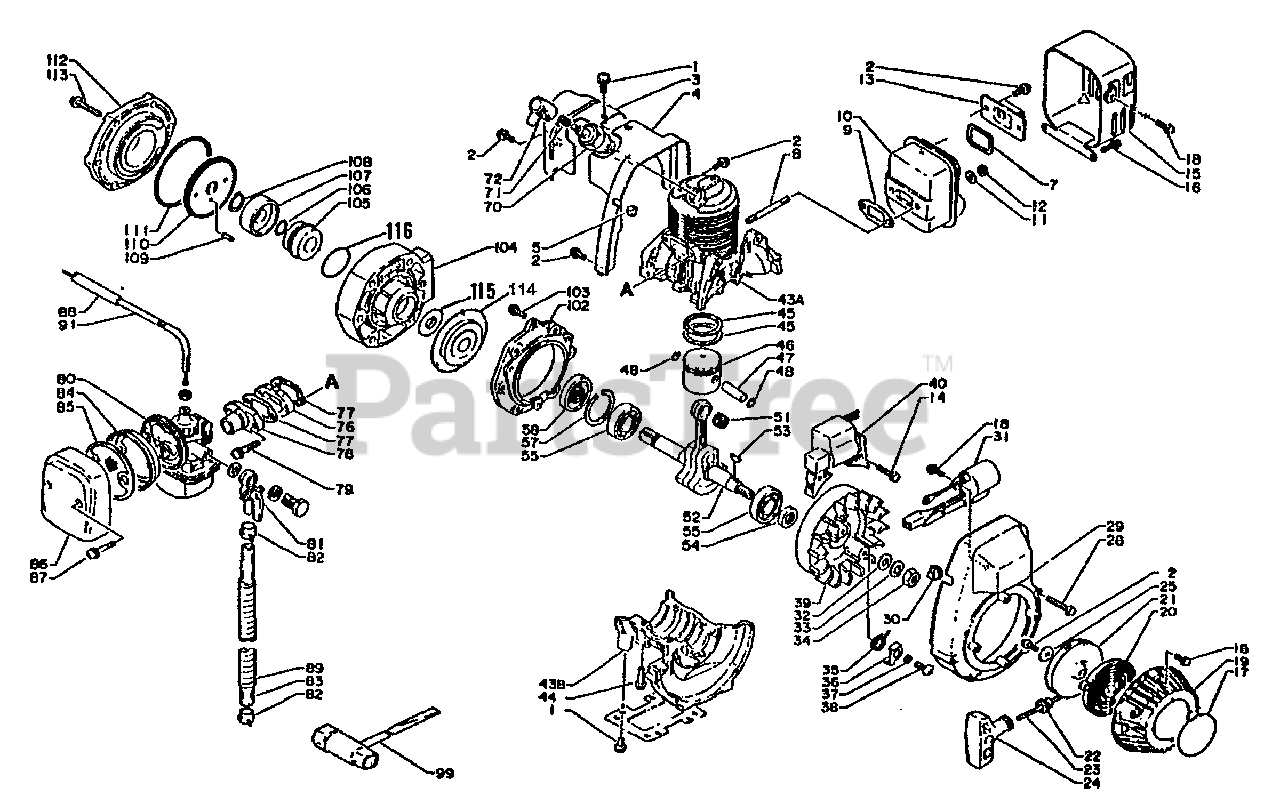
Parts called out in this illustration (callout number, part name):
1	SCREW 5×10
2	SCREW 4×10
3	PLATE, GUIDE
4	COVER, CYLINDER
7	GASKET, EXHAUST
8	BOLT, STUD
9	GASKET, MUFFLER
11	WASHER 5.5×12×0.8
12	NUT, LOCK M5
13	COVER, MUFFLER
14	SCREW 4×20
15	COVER, MUFFLER
16	SCREW 4×12
17	LABEL, ECHO
18	SCREW 4×14
19	CASE, RECOIL STARTER
20	SPRING, RECOIL
21	REEL, ROPE
22	GUIDE, ROPE
23	ROPE, STARTER 3.0×850
24	GRIP, STARTER
25	WASHER 4.1×15.5×1T
28	SCREW 4×40
29	COVER, FAN
31	COIL, IGNITION
32	WASHER 8.5×16×1.2
33	WASHER, SPRING 8
35	SPRING, RATCHET
36	PAWL, STARTER
37	SPACER 5.2×8×2.1
38	SCREW 5×14
39	FLYWHEEL
40	COIL, IGNITION
43	CASE, CYLINDER SET
43A	CASE, CYLINDER SET
43B	CASE, CYLINDER SET
44	SCREW 5×30
45	RING, PISTON
47	PIN, PISTON
48	RING, SNAP
51	BEARING, NEEDLE
52	CRANKSHAFT
54	SEAL, OIL
55	BEARING, BALL - 6201 C3
57	RING, SNAP Ø32
58	SEAL, OIL 12
70	SPARK PLUG - BM6A
71	TERMINAL, SPARK PLUG CAP
72	CAP, SPARK PLUG
76	INSULATOR
78	ADAPTER, INTAKE
79	SCREW 5×25
80	CARBURETOR
81	VALVE, FUEL
82	CLAMP
83	PIPE, FUEL
84	CASE, AIR FILTER
85	FILTER, AIR
86	COVER, AIR FILTER
87	SCREW 4×28
88	TUBE, COVER
91	CABLE, THROTTLE
99	T-WRENCH 10×19 MM
102	BRACKET, PUMP
103	SCREW 5×16
104	CASE, PUMP
105	SEAL, MECHANICAL
106	O-RING
107	PLATE, DRIVE
108	E-RING 12
110	IMPELLER
111	O-RING
112	LID, PUMP
113	SCREW 5×40
